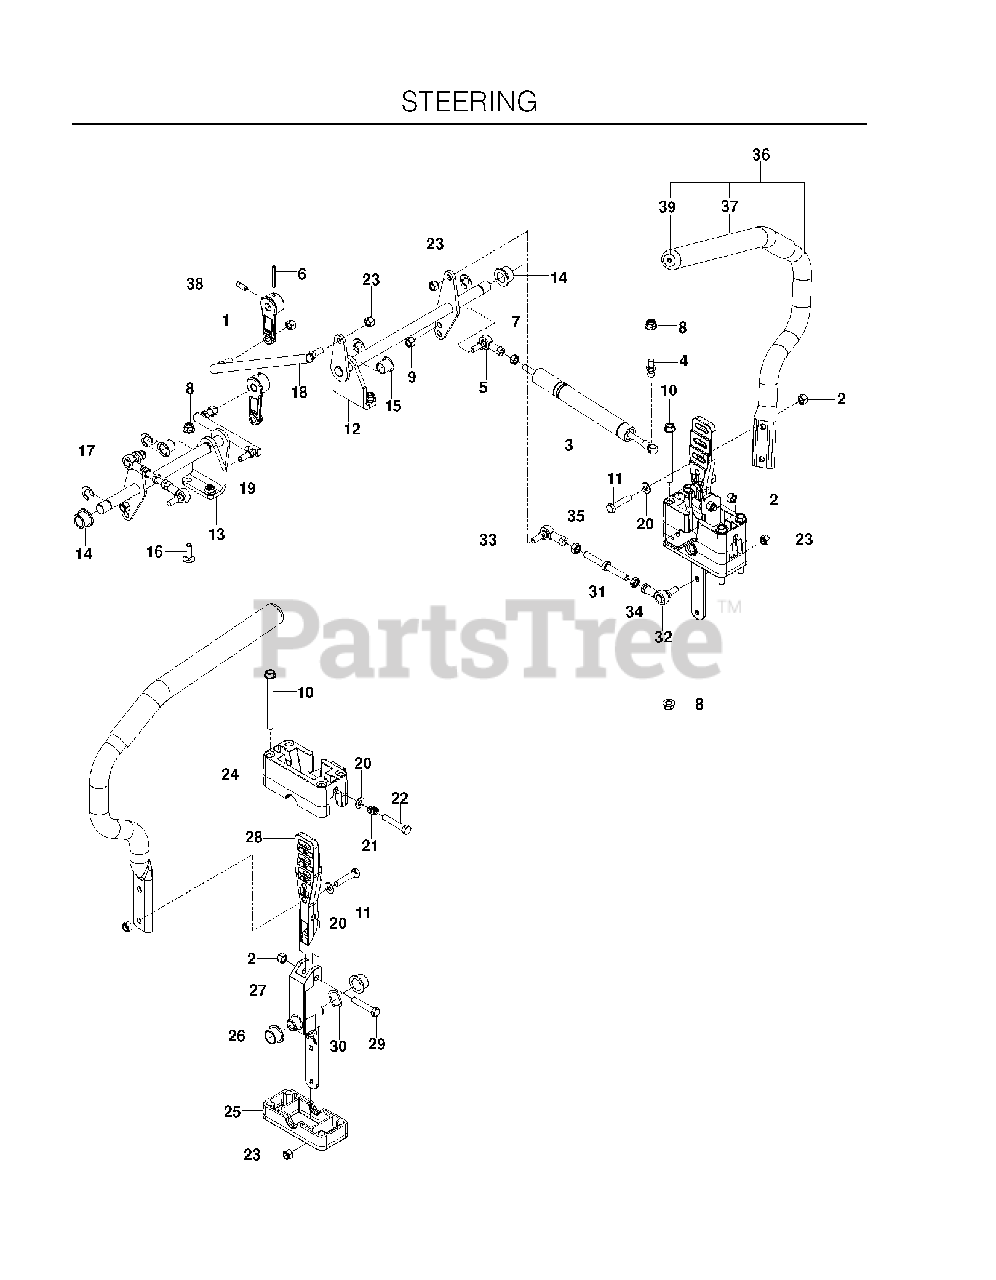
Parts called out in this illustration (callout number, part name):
1	ARM, PUMP
2	NUT 5/16 NYLOC
3	DAMPENER W/SPRING
4	STUD.BALL.10MM
5	ROD END
6	PIN, SPIRAL, 5/32 X 1 1/2
7	NUT M8 X 1.25 STD HEX
8	5/16-18 NYLOC FLANGE NUT
9	NUT M8 NYLOC
10	HHFS 5/16-18 X 3 3/4
11	CAPSCREW 5/16 X 1/1/2 HEX HEAD
12	CONTROL WLDMT, LT
13	CONTROL WLDMT, RT
14	BUSHING, FLANGED, 5/8
15	BUSHING, CLIP, 5/8
16	RHSNB 5/16C X 1
17	E-RING 5/8
18	LINK, MOTION, LT
19	LINK, MOTION, RT
20	FLAT WASHER 5/16 SAE
22	HCS 5/16-18X1-3/4 TPBLT
23	NUT 5/16-24 CNTRLK
24	BLOCK, UPPER
25	BLOCK, LOWER
26	BEARING, FLANGE
27	PIVOT SECTION, DR CNTRL
28	MOUNT, DR CNTRL HANDLE
29	HCS 5/16C X 1 3/4
30	WASHER, .825 X 1.087, WAVE
31	JACK SCREW
32	SPHERICAL ROD END, LH
33	SPHERICAL ROD END, RH
34	NUT 5/16F LEFTHAND
35	NUT 5/16F
36	LEVER.DRIVE.W/GRIP
37	GRIP, FOAM (GROUND) 15
38	SCREW 5/16C X 5/8 SQ HEAD
39	END PLUG 15/16` (BLACK)
